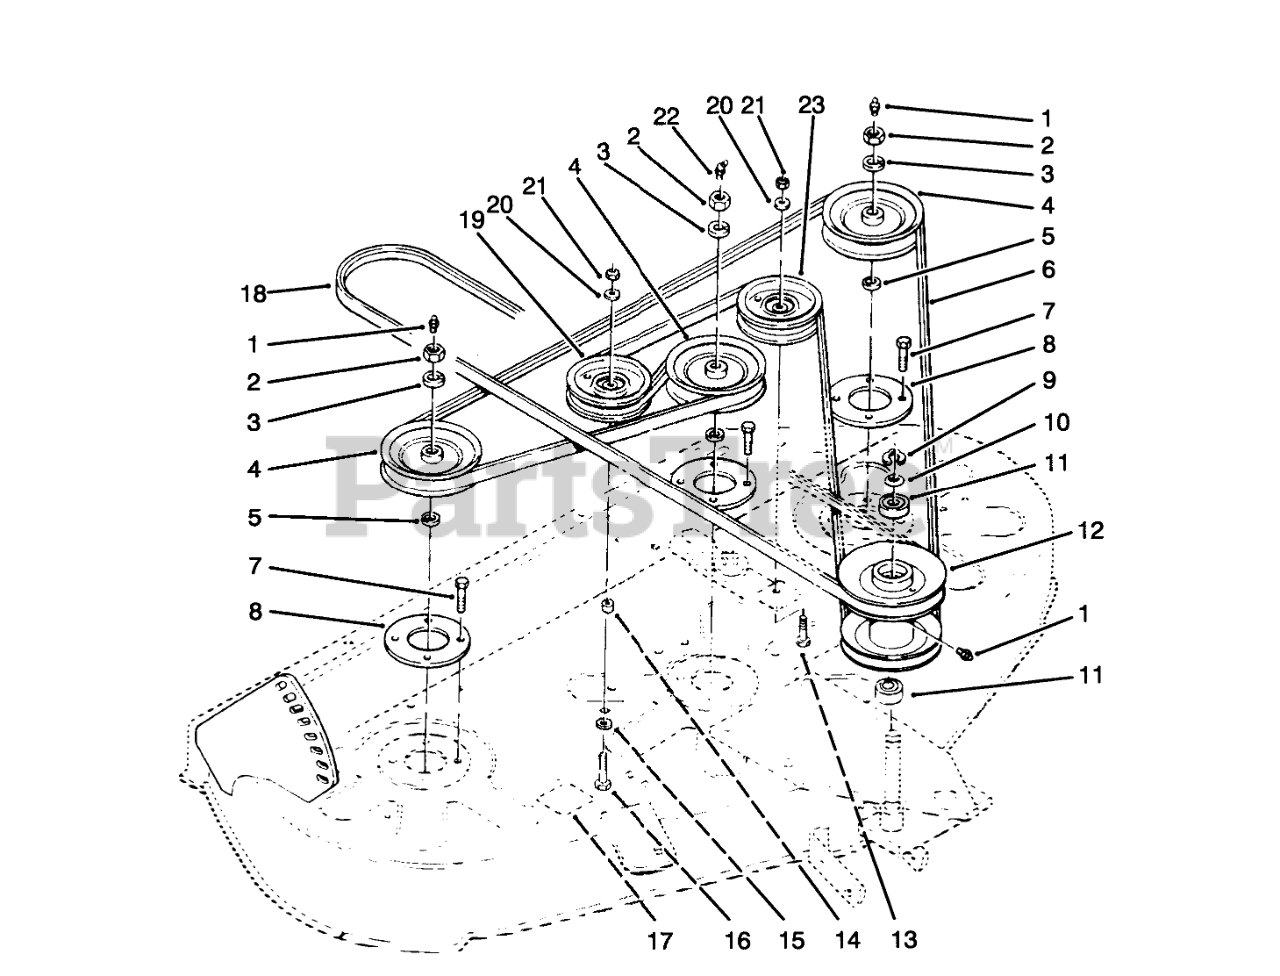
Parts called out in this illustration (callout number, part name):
1	FITTING-GREASE
2	NUT-JAM
3	WASHER-LOCK
4	Pulley
5	Washer
6	V-BELT
7	SCREW-HH
8	SPACER-SPINDLE
9	RETAINING RING
10	O RING
11	BEARING-BALL
12	PULLEY-COUNTER SHAFT
13	SCREW-HH
14	SPACER
15	WASHER
16	SCREW-HH
17	DECAL-BELT INSTALL
18	V-BELT
19	Pulley-Idler
20	WASHER-FLAT
21	NUT-LOCK, NI
22	FITTING-GREASE
23	PULLEY-FLAT IDLER
